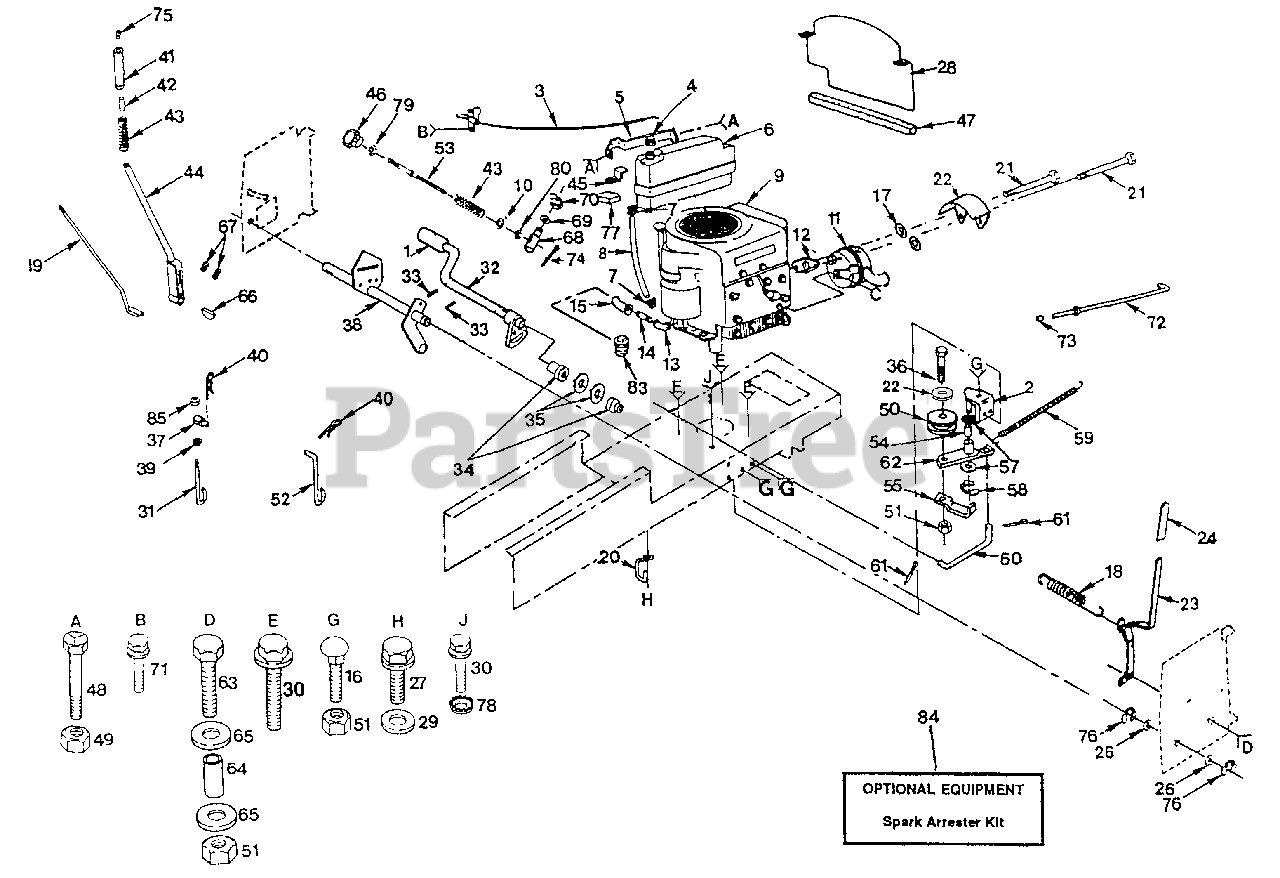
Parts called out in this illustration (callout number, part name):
1	Pedal Cover
2	Bracket Assembly, Clutch
3	Control, Throttle
4	Fuel Cap
5	Support, Tank, Fuel
6	Tank, Fuel
7	Hose Clamp
8	Fuel Line
9	Engine Briggs & Stratton, Type No. 0412-01
10	Washer 13/32 x 5/8 x 16 Ga.
12	Gasket, Exhaust
13	45° Street Elbow 3/8 NPT
14	Std. Pipe Nipple 3/8 - 18 NPT x 3 1/2
15	90° Elbow 3/8 NPT
16	Bolt, Carriage 3/8 - 16 x 3/4
17	Washer Lock 15/32 x 11/16 x 16 Ga.
18	Spring, Extension
19	Rod Assembly, Lever
20	Retainer, Belt, Chassis L.H.
21	Bolt 5/16 - 18 x 5/8
22	Shield, Heat, Muffler
23	Handle, Clutch Attachment
24	Grip, Handle
25	Washer 13/32 x 13/16 x 16 Ga.
26	Washer 29/32 x 1 - 1/4 x 16 Ga.
27	Screw, Hex Washer Thrd. Rolling 3/8-1 6 x 3/4
28	Baffle, Vertical
29	Washer 13/32 x 13/16 x 12 Ga.
30	Screw, Hex Washer Hd. Thread Rolling 3/8 - 16 x 1 - 1/4 Type TT
31	Link, Lift, Adjustable
32	Shaft, Pedal, Foot
33	Roll Pin 3/16 x 1
34	Bearing, Nylon
35	Washer, 21/32 x 1 x 16 Ga.
36	Bolt, Fin Hex 3/8 - 16 x 2 - 3/4
37	Trunnion, Lift
38	Shaft, Assembly Lift
39	Nut, Hex Jam 7/16 - 20
40	Retainer Spring
41	Grip, Handle
42	Plunger, Lever, Hand
43	Spring
44	Lever Assembly, Hand Kit
45	Brace, Tank
46	Handle, Adjust Lift
47	Strip, Foam 14.5"
48	Bolt, Hex 5/16 - 18 x 3/4 Gr. 5
49	Locknut 5/16 - 18 Gr. B
50	Pulley, Idler
51	Nut, Crownlock 3/8 - 16
52	Link, Lift
53	Rod, Adjust, Lift
55	Retainer, Belt
57	Washer, Hardened
58	Ring, Klip
59	Spring, Return Clutch
60	Link, Clutch
61	Pin, Cotter 1/8 x 3/4
62	Arm, Asm. Idler
63	Bolt Hex 3/8 - 16 x 1 - 1/2
64	Bushing, Handle, Clutch
65	Washer 3/8 x 1 x 12 Ga.
66	Woodruff Key 1/4 x 1
67	Set Screw, Hex Socket Forged Headless 3/8 - 16 x 3/8
68	Trunnion, Stop, Depth
69	Washer 15/32 x 3/4 x 16 Ga.
71	Screw Hex Thread Cutting 1/4 - 20 x 5/8
72	Rod, Brake, Park
73	Plunger Cap
74	Cotter Pin 3/32 x 1/2
75	Button, Plunger
77	Pad, Spacer
78	Washer, Lock 3/8 - Ext. Tooth
79	Nut, Hex Jam 3/8 - 16
80	Nut,
83	Oil Drain Plug
84	Spark Arrester Kit
85	Nut, Jam Crownlock 7/16 - 20
